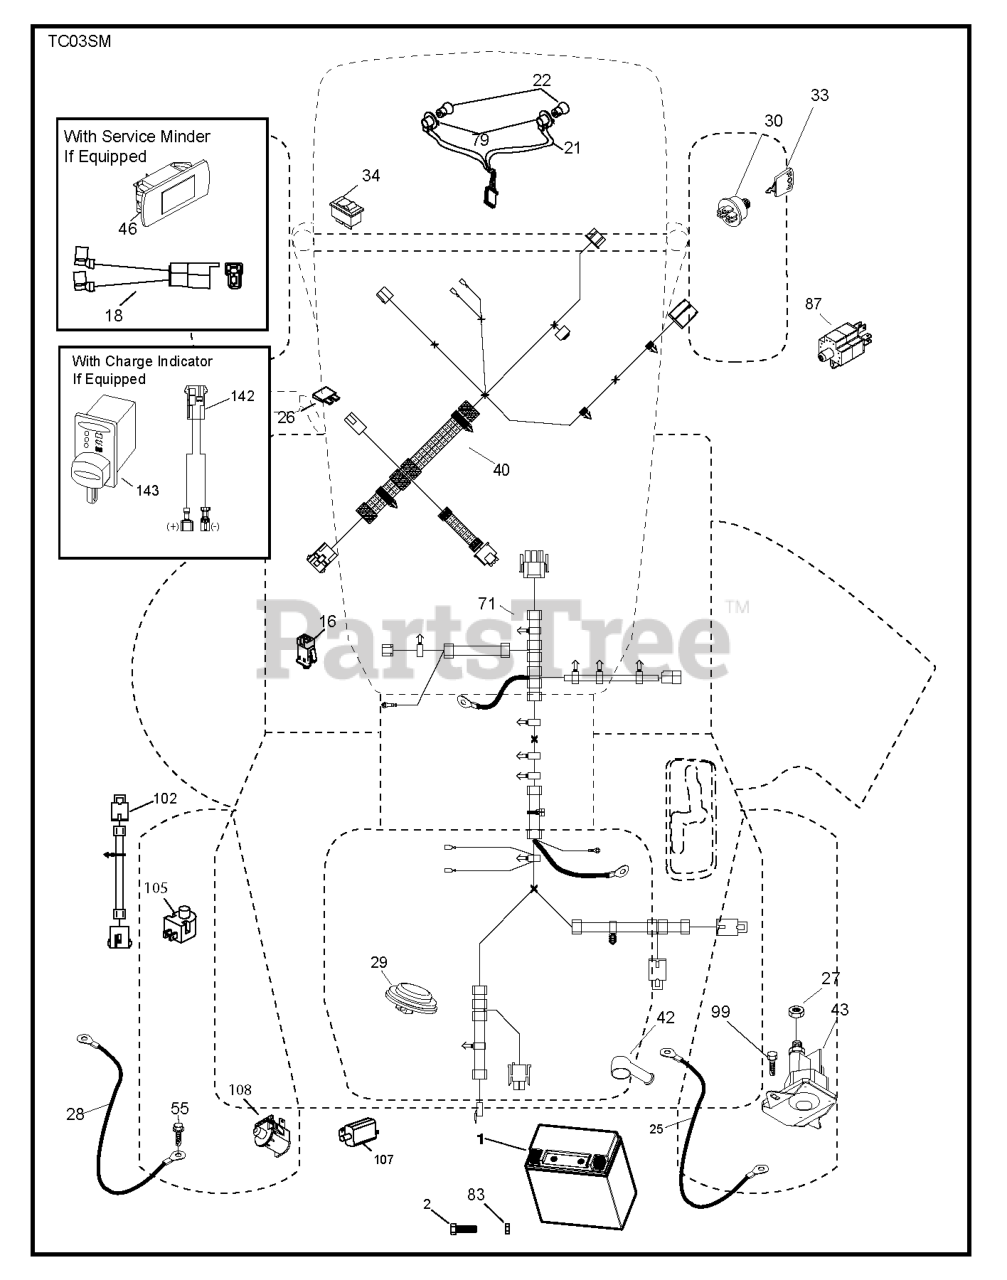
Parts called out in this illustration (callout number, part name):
1	BATTERY BATTERY 14AH 12V LEOC
16	SWITCH INTERLOOK PUSH-IN
21	HARNESS.LIGHT W/4152J BULBS
25	CABLE.BATT.8GA.RED9.CRD2.5
26	FUSE 20AMP
28	CABLE.BATT.BLCK10.SLV.CRD2.5
29	SWITCH.SEAT.DP W/RAMPS
29	SWITCH.SEAT.DELTA.OPC.
30	SWITCH.IGN.DELTA.W.LGH.ROS
33	KEY.CHAIN.BLISTER.PACK.GEN.INT
33	KEY.CHAIN.BLISTER.PACK.GEN.USA
40	RP HARNESS.ELECTRICAL.DASH.SRD
42	TERMINAL COVER
46	GUAGE.SRVCMNDR.HRMTR.
55	SCREW 5/16"
71	HARNESS
71	HARNESS.CHASS.CRD.TEX.RDY.STRT
79	BULB HOLDER ASM.
83	NUT SQUARE M6, 11X8.5 ZPB
87	RP SWITCH.RAILMOUNT.NO-NC-NC
99	SCREW
102	HARNESS ASSY
105	REVERSE SWITCH
107	.WITCH.FULL BAGGER.INDICATOR
108	SWITCH.SNPMT.NCBT.CRD.MTL.BKPL
